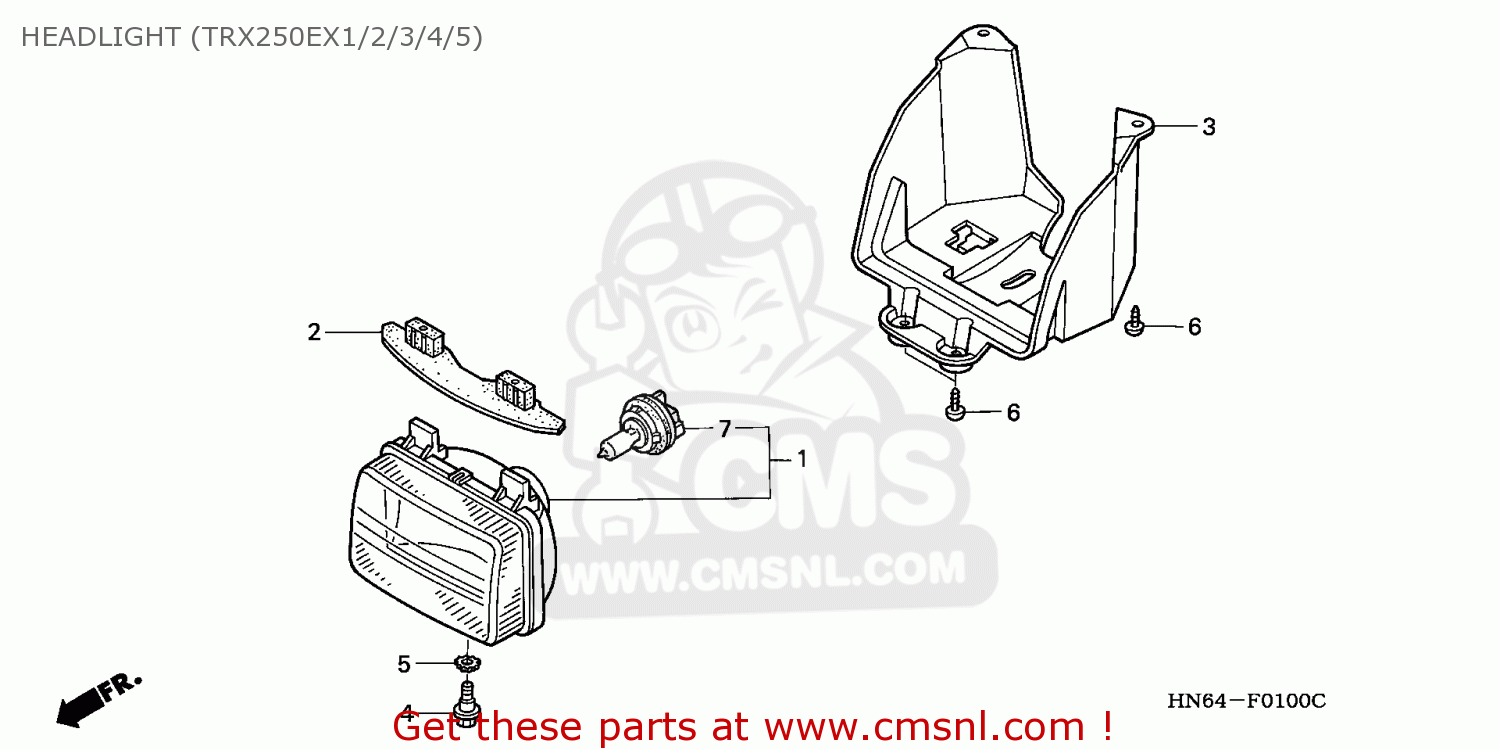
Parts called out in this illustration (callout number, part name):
1	LIGHT ASSY,HEAD
2	RUBBER,H/L
3	COVER,HEAD LIGHT
4	SCREW,ADJUST
5	WASH,LOCK 6MM
6	SCREW,TAPPING,5X16
7	BULB,SOCKET COMP.
